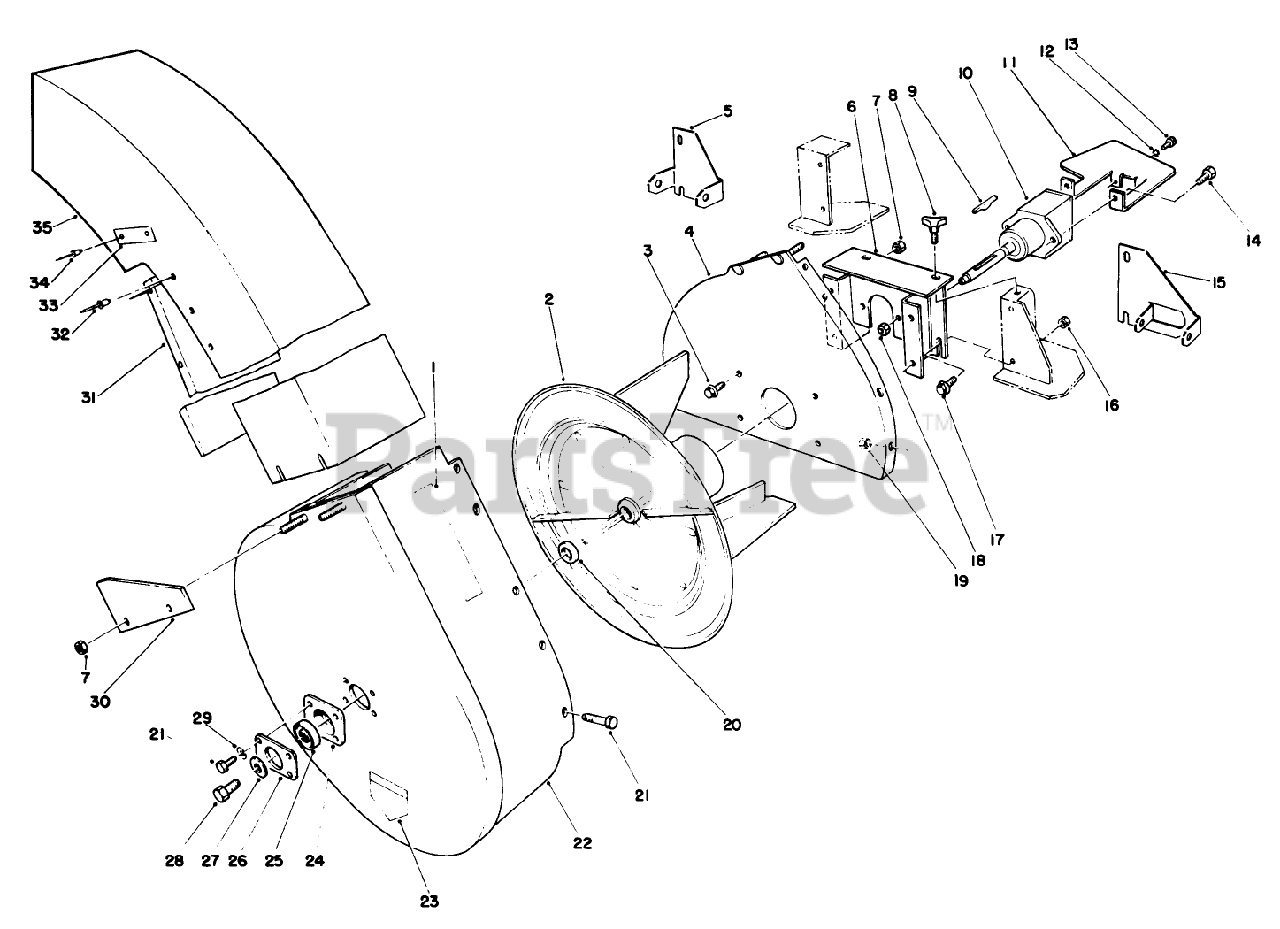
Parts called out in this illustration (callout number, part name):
1	DECAL
2	Impeller
3	SCREW-HHF
4	Plate-Mounting
5	Bracket-Pivot LH
6	Mount-Blower
7	NUT-LOCK, NI
10	Asm-Gear Box
11	Cover-Gear Box
12	WASHER-LOCK, EXT
14	SCREW-HH
15	Bracket-Pivot RH
16	NUT-JAM
17	SCREW-HHF
18	NUT-LOCK, NI
19	NUT-LOCK, NI
20	SPACER-BEARING
21	SCREW-HH
22	Housing-Blower (Incl. Ref. #1 & 23)
23	DECAL-DANGER
24	CUP-BEARING
25	BEARING-BALL
26	Cover-Plate
27	SPACER
28	SCREW-HH, LOCK
29	WASHER-LOCK
30	Bracket
31	Deflector-Chute
33	PLATE - WARNING
34	RIVET-POP
35	Chute Assembly (Incl. Ref. #32-34)
